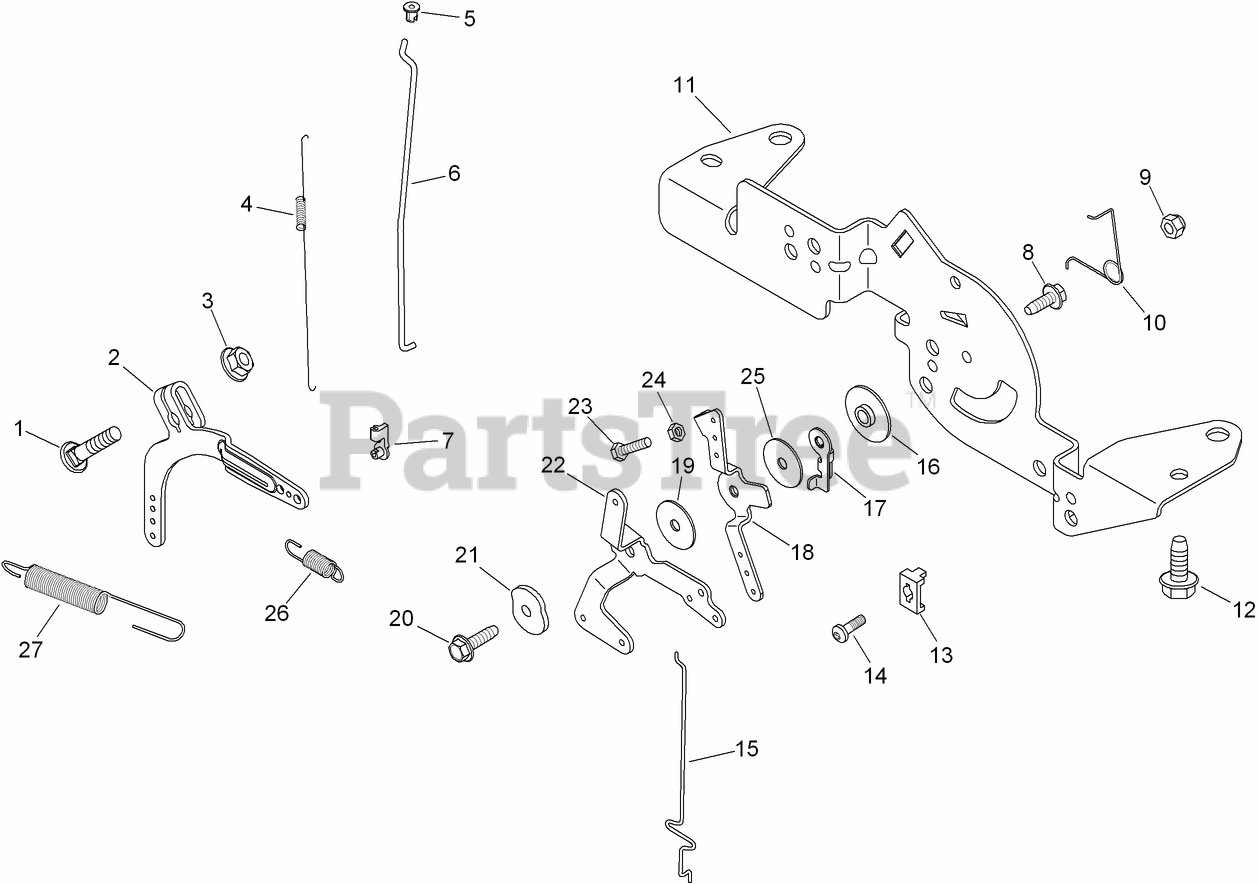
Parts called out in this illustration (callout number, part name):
1	BOLT-SQ NECK, RD HD (M6X1.0X25)
2	LEVER-GOVERNOR
3	NUT-FLANGE (M6X1.0)
4	SPRING-LINKAGE
5	BUSHING-LINKAGE, THROTTLE
6	LINKAGE-THROTTLE
7	BUSHING-RETAINING, LINKAGE
8	SCREW-FLANGE, THREAD FORMING (M5X0.8X16)
9	NUT-LOCK (M5X.8)
10	SPRING-RETURN, CHOKE
11	BRACKET-CONTROL
12	SCREW-FLANGE, THREAD FORMING (M6X1.0X16)
13	CLAMP-CABLE
14	SCREW-LBD, THD FRM (M5X0.8X16)
15	LINKAGE-CHOKE
16	CONTROL SPACER ASM
17	LEVER-ACTUATOR, THROTTLE
18	LEVER-CONTROL, THROTTLE
19	WASHER-FLAT (5.5MM)
20	SCREW-FLANGE, THREAD FORMING (M5X.8X20)
21	WASHER-SPRING (1/4)
22	LEVER-CHOKE
23	SCREW-SLOTTED HEAD (M4X0.7X25)
24	NUT (M4X0.7)
25	WASHER-FLAT (5MM)
26	SPRING-GOVERNOR
27	SPRING-GOVERNOR
